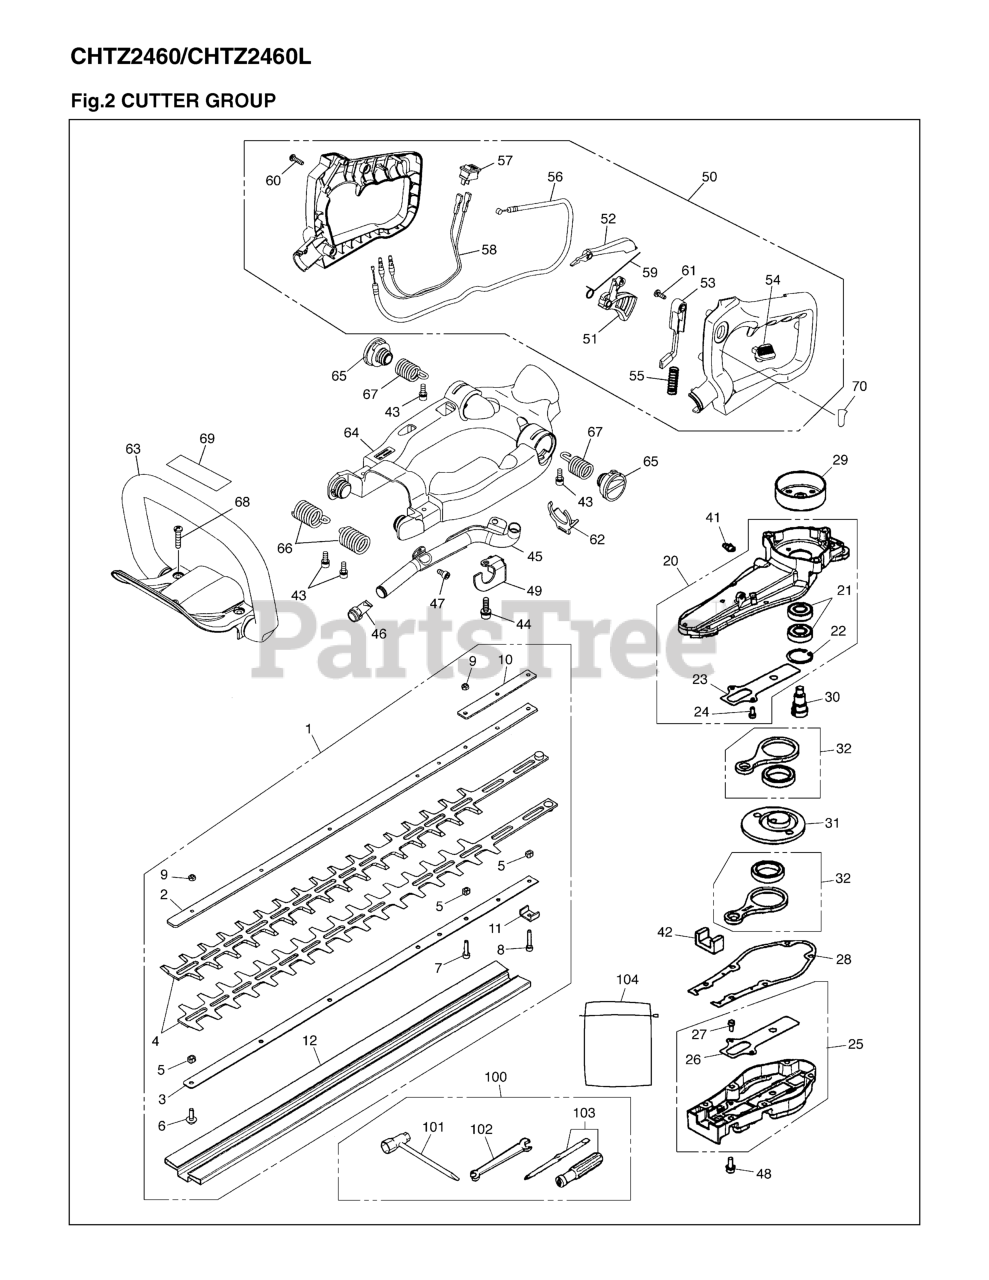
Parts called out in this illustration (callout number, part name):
1	BLADE ASSY
2	PLATE, UPPER
3	PLATE, LOWER
5	SPACER
7	BOLT (RPLS 28501
11	BRACKET (RPLS T4
12	COVER, BLADE
20	GEAR HOUSING COMP
24	BOLT
25	CAP COMP
27	BOLT
30	GEAR DRIVE
31	GEAR DRIVEN
41	FITTING, GREASE
45	EXHAUST PIPE
46	ARRESTER
47	BOLT
50	HANDLE-REAR-A
51	LEVER-THROTTLE
52	ARM
53	LEVER-LOCK
54	KNOB
58	CHORD COMP.
60	SCREW
61	SCREW (RPLS 5003
63	HANDLE F
65	HOLDER-REAR
69	LABEL, NAME
100	TOOL KIT ASSY
102	SPANNER,8 x 10(R
103	SCREWDRIVER
